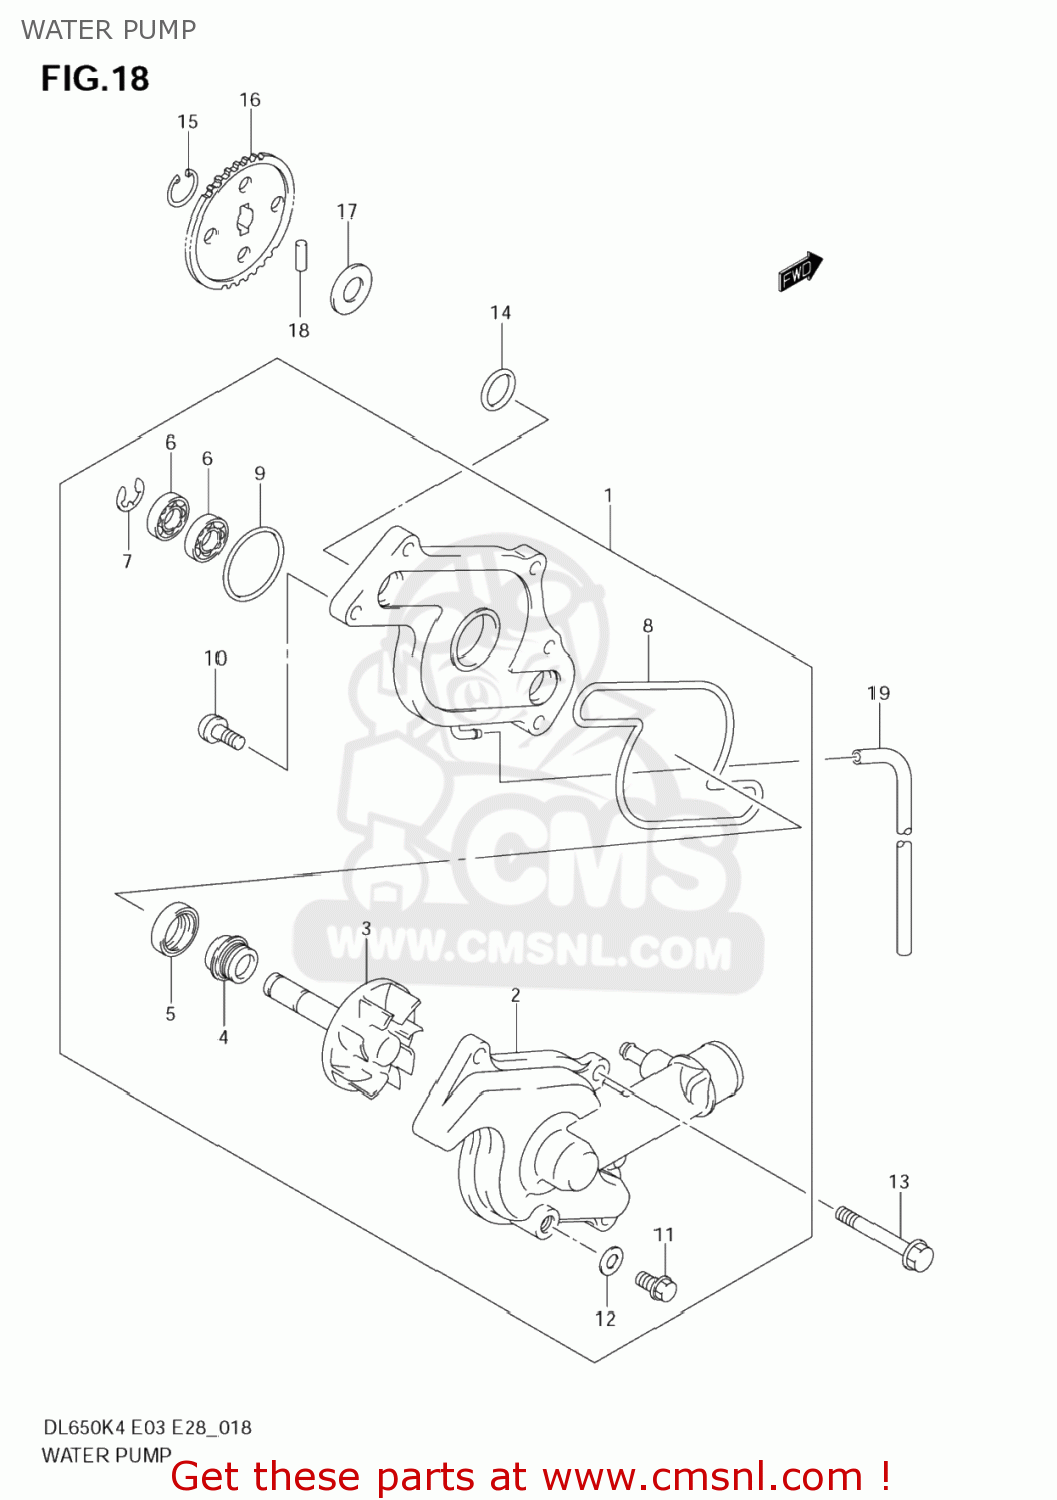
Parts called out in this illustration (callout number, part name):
1	PUMP ASSY,WATER
2	CASE,WATER PUMP
3	IMPELLER/SHAFT
4	SEAL,MECHANICAL
5	SEAL,OIL(10X21X5)
6	BEARING
7	E RING
8	O RING
9	O RING,WATER PUMP HOLDER
10	SCREW 6X16
11	BOLT,DRAIN
12	GASKET(8.2X14X1) (NAS)
13	BOLT(6X55)
14	O RING(D:2.4,ID:21.8)
15	CIRCLIP,10MM
16	GEAR,WATER PUMP DRIVEN
17	SHIM(10X18X0.5)
18	ROLLER(4X13.8)
19	HOSE(3.5X6.5X600)
